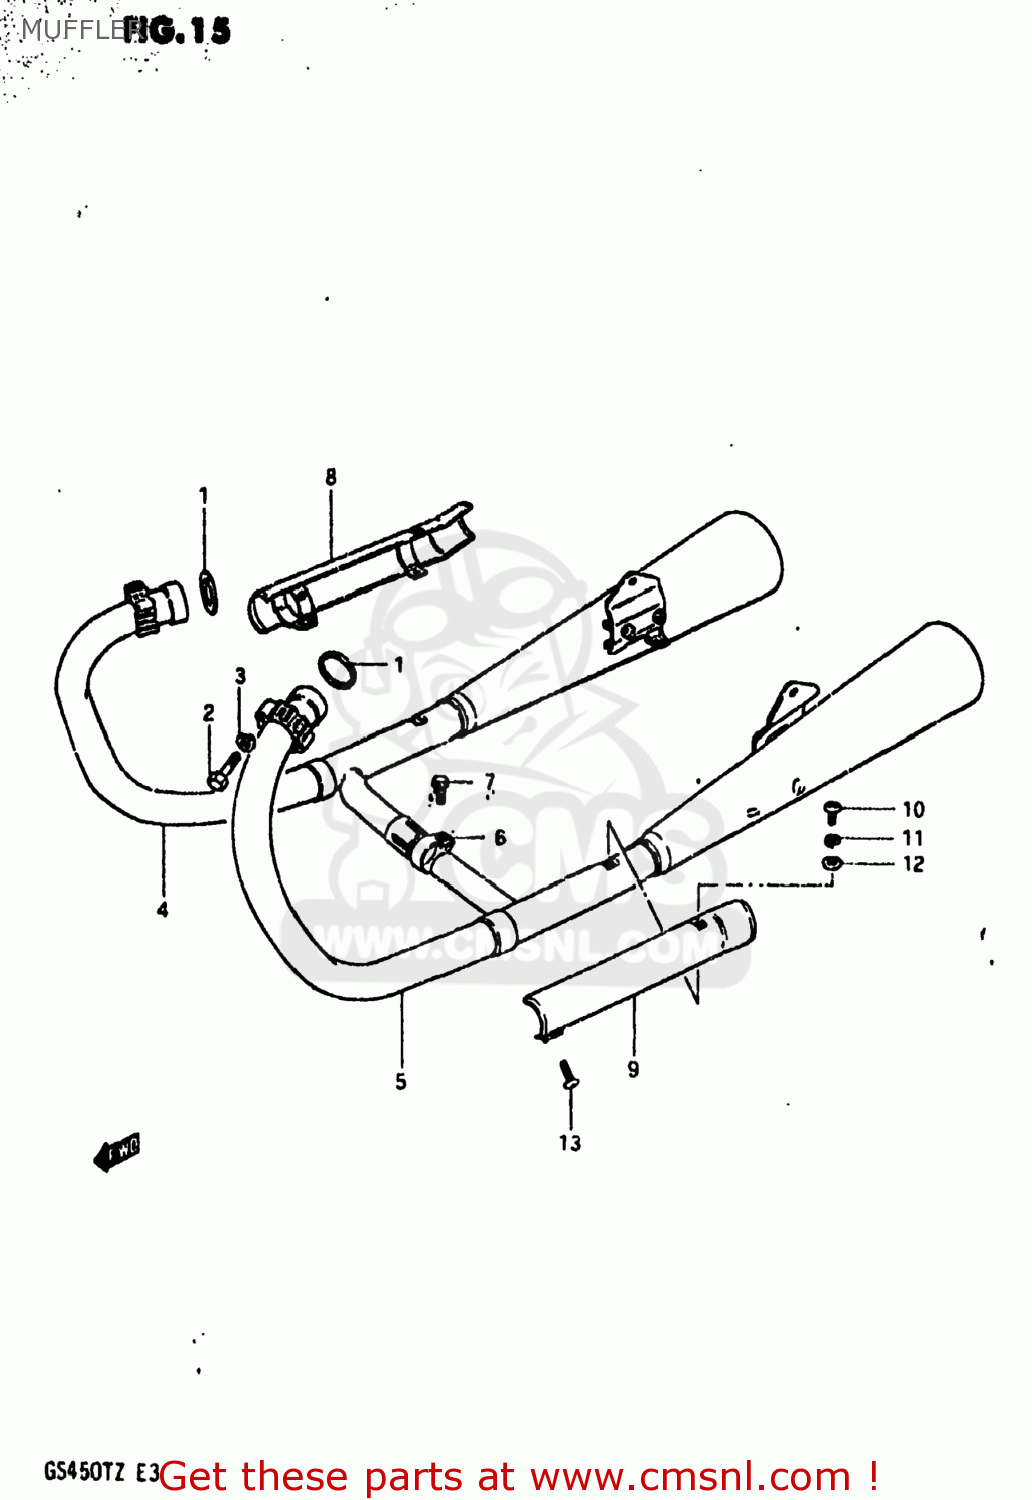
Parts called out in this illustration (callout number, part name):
1	GASKET,EXHAUST PIPE (NAS)
2	BOLT
3	LOCK WASHER
4	MUFFLER ASSEMBLY
5	MUFFLER ASSEMBLY
6	CLAMP
7	BOLT
8	COVER,MUFFLER
9	COVER,MUFFLER
10	SCREW
11	LOCK WASHER
12	WASHER
13	SCREW
